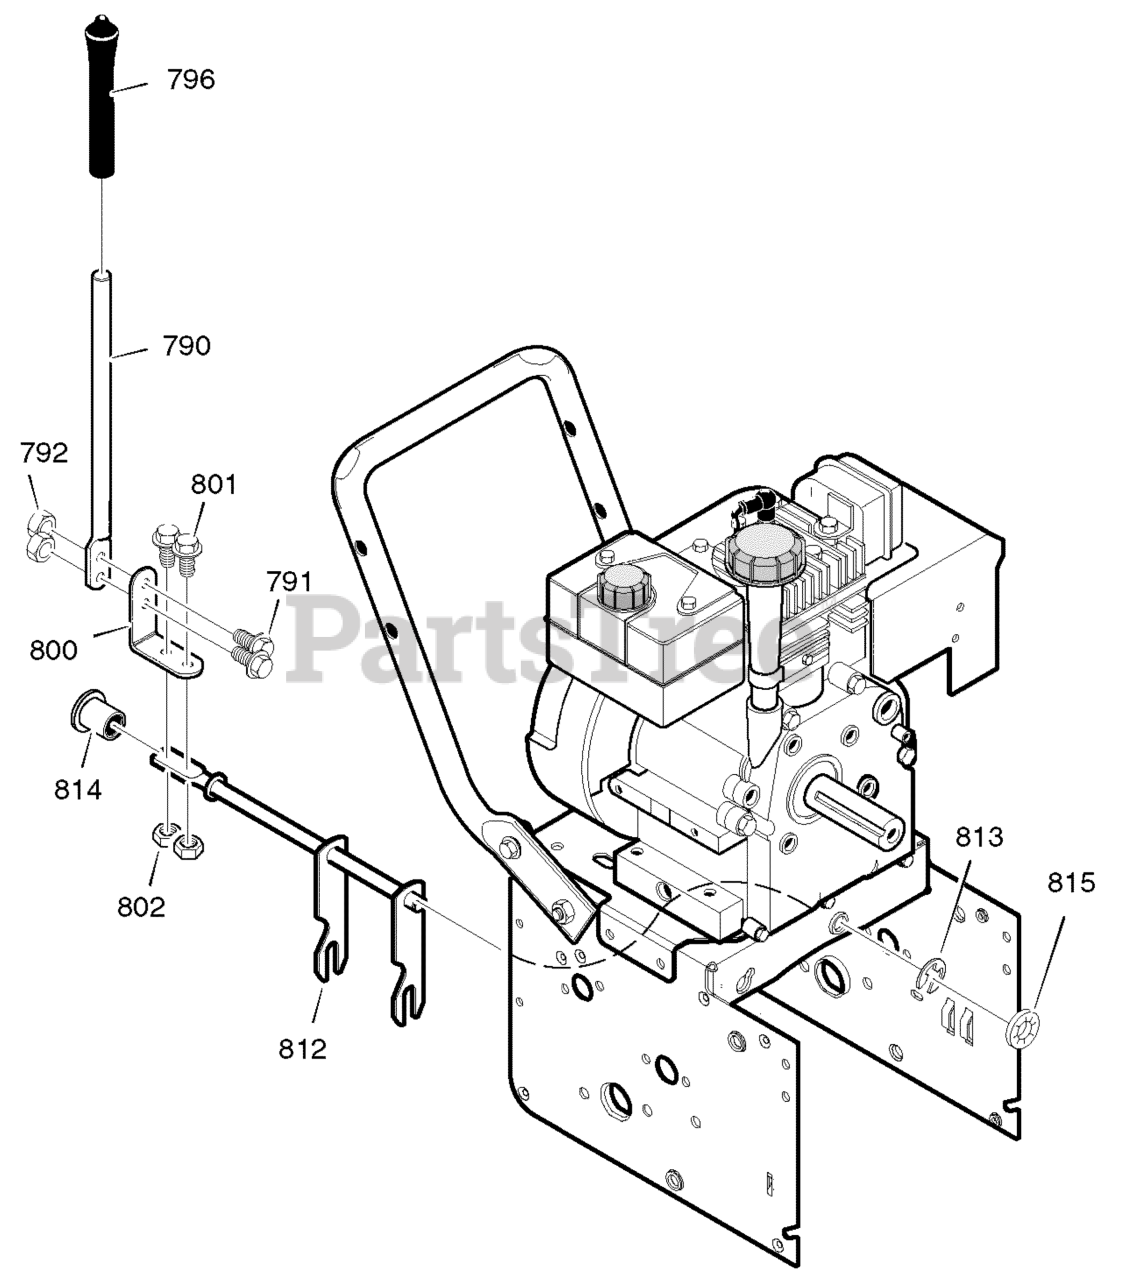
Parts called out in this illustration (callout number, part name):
790	ROD, SHIFT
791	SCREW, 1/4-20X.75
792	NUT, 1/4-20
796	KNOB, SLIP
800	LEVER, SPRING
801	SCREW, 1/4-20X.75
802	NUT, 1/4-20
812	ROD ASSY., SPEED SELECT
813	RETAINER, RING
814	BEARING, FLANGED
815	NUT, SPEED
